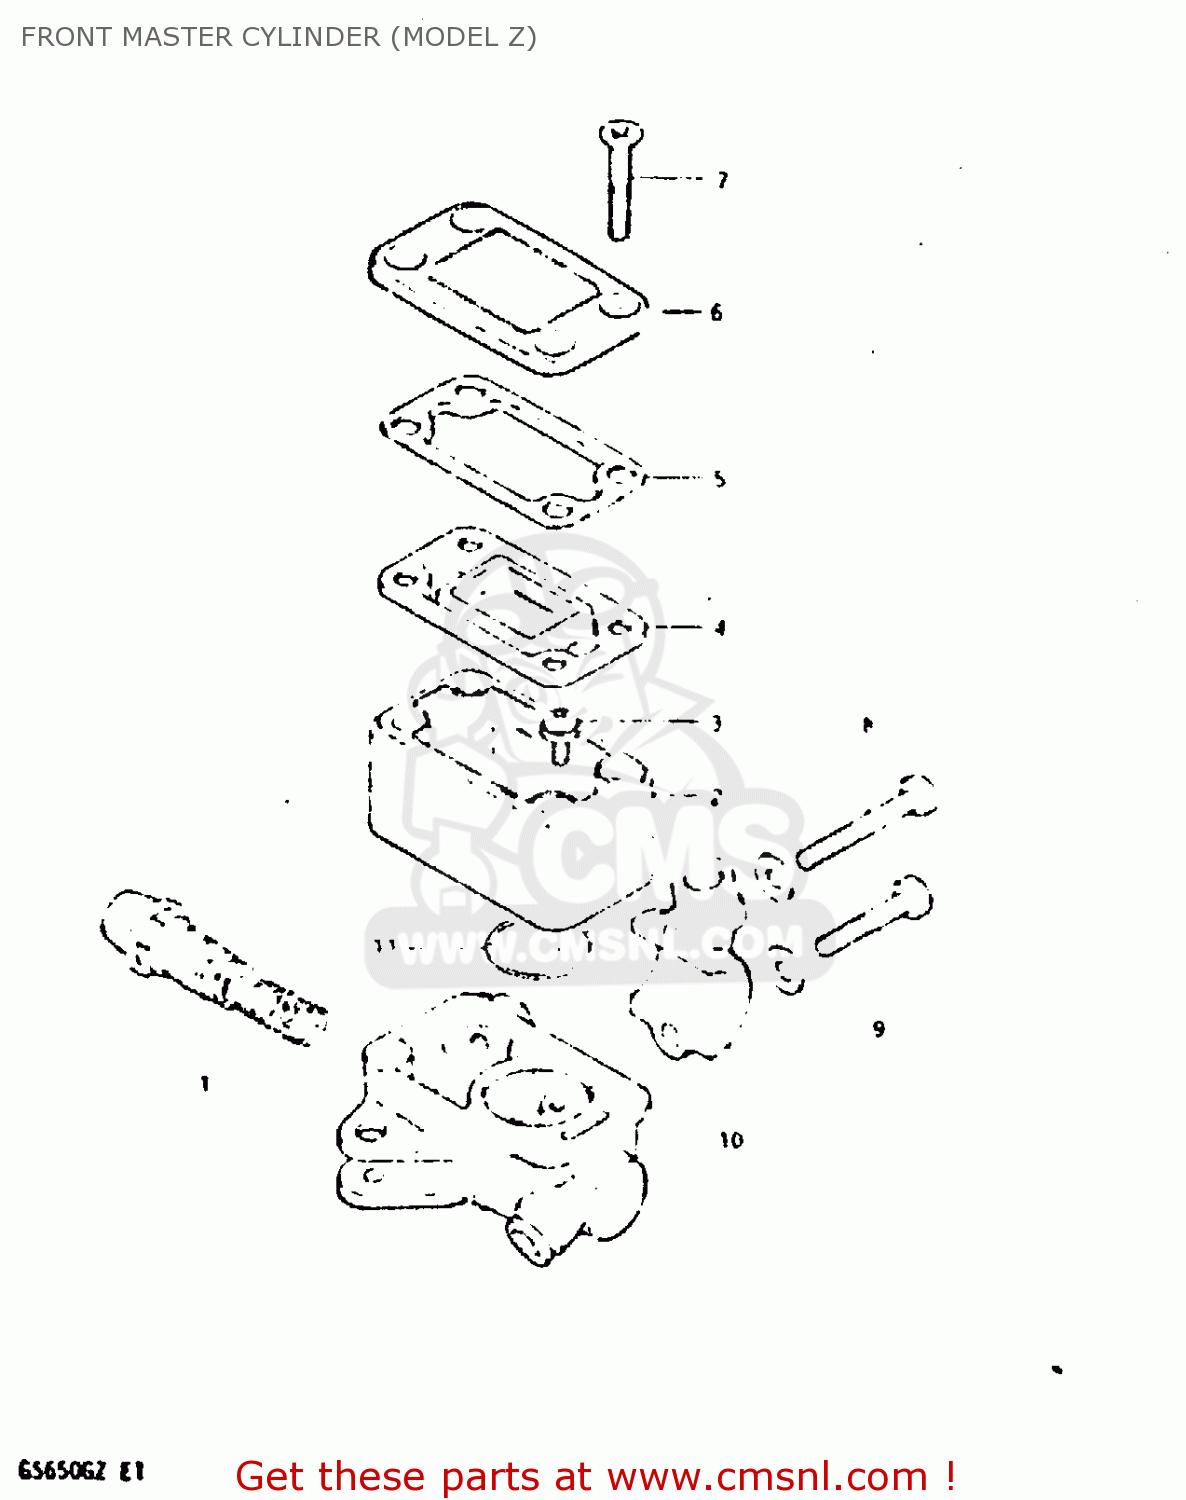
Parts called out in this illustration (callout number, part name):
1	PISTON & CUP SET
2	RESERVOIR
3	SCREW,MASTER C
4	DIAPHRAGM
5	PLATE,DIAPHRAGM
6	CAP
7	SCREW
8	BOLT,MASTER CYLINDER H
9	BOLT,MASTER CYLINDER H
10	HOLDER
11	O RING
